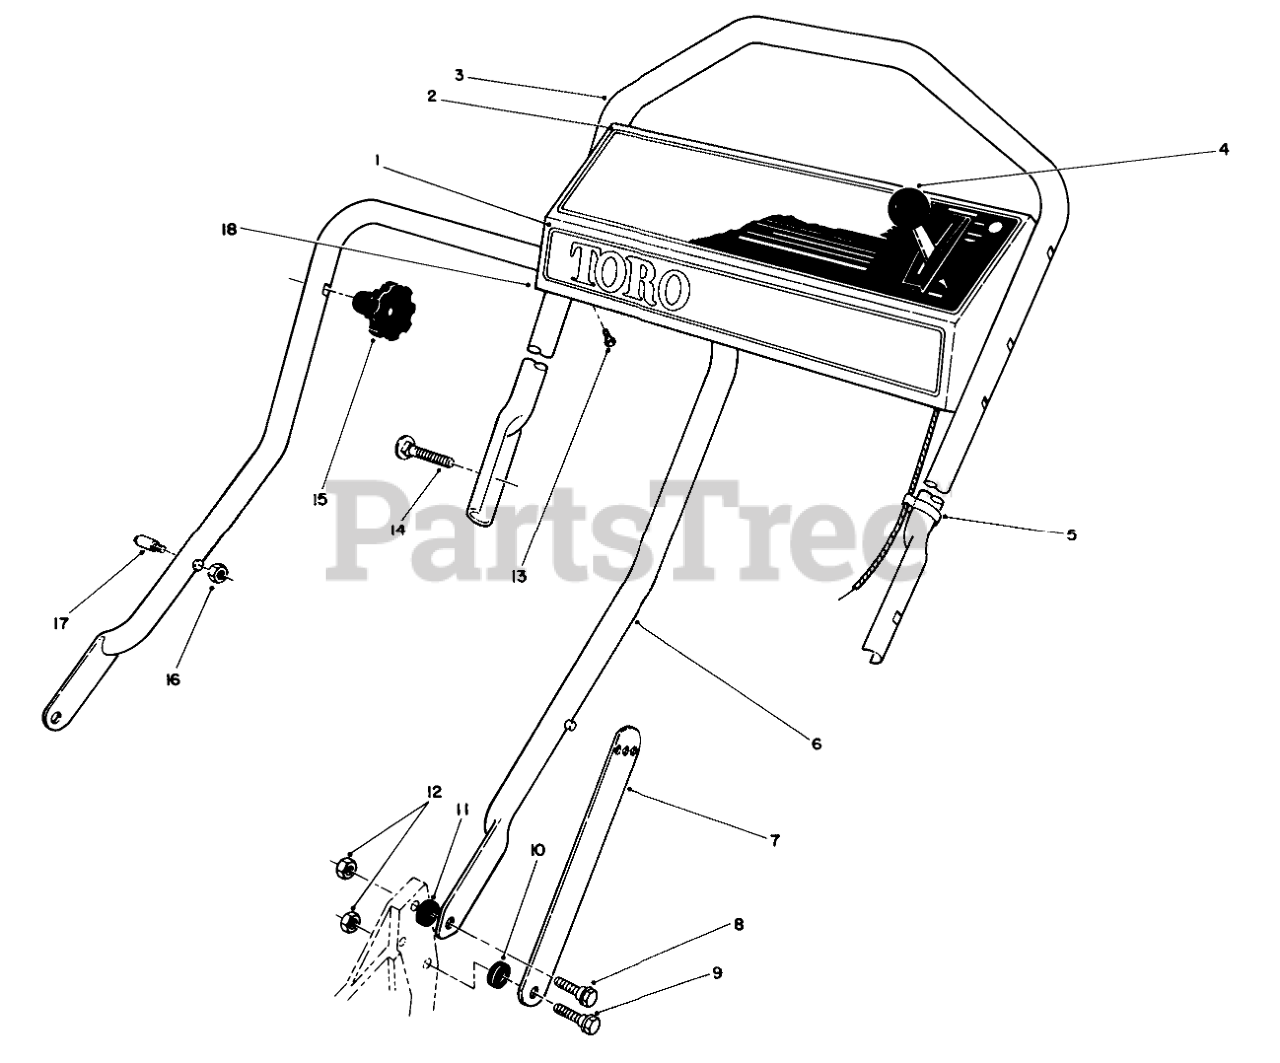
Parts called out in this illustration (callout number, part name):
1	Decal-Toro
2	Decal-Control Panel
3	Upper Handle Assembly (Incl. Ref. #4)
4	THROTTLE CONT-SERVICE
5	BOWDEN CLIP
6	Lower Handle Assembly (Incl. Ref. #17-18)
7	Handle Latch
8	SCREW-SHOULDER
9	SCREW-SHOULDER
10	SPACER
11	SPACER
12	NUT-LOCK, NI
13	SCREW-HWHTF
14	5/16-18 X 2 HNDLE SCREW
16	NUT-LOCK, NI
17	HANDLE PIN
18	Control Panel
